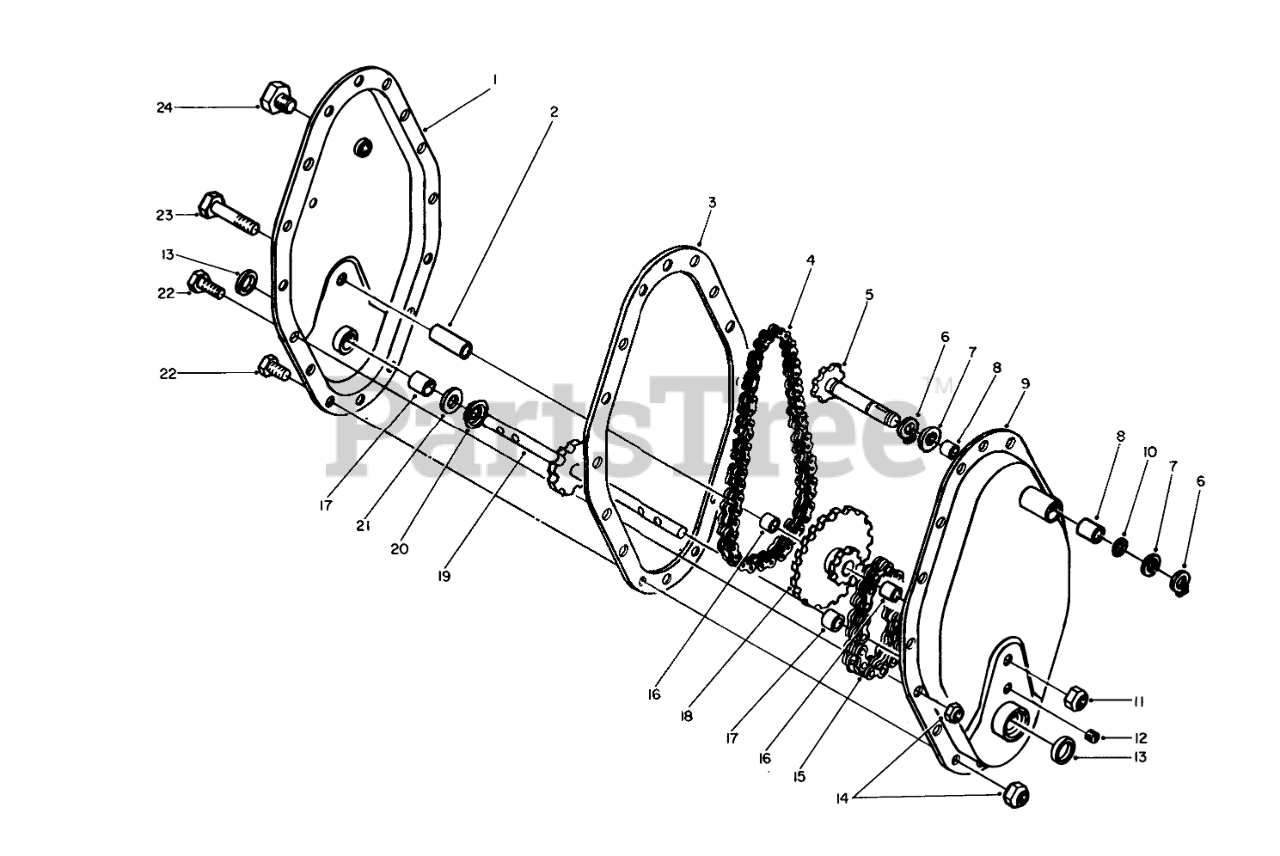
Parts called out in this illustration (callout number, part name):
1	Chain Case-R.H. w/Bearings
2	Idler Sleeve
3	Gasket
4	Chain-Upper
5	Input Shaft
6	Retaining Ring
7	Washer
8	BEARING-NEEDLE
9	Chain Case-L.H. w/Bearings
10	0 Seal-Input Shaft
11	PART CAT OPC
12	Plug-Pipe
13	Seal
14	NUT-LOCK, CONE
15	Chain-Lower
16	NEEDLE BRG
17	Bearing
18	Sprocket (Incl. Ref. #16)
19	Tine Shaft
20	Spacer Cup
21	Shim-Gear
22	SCREW-HH
23	Capscrew
24	SCREW-HH
